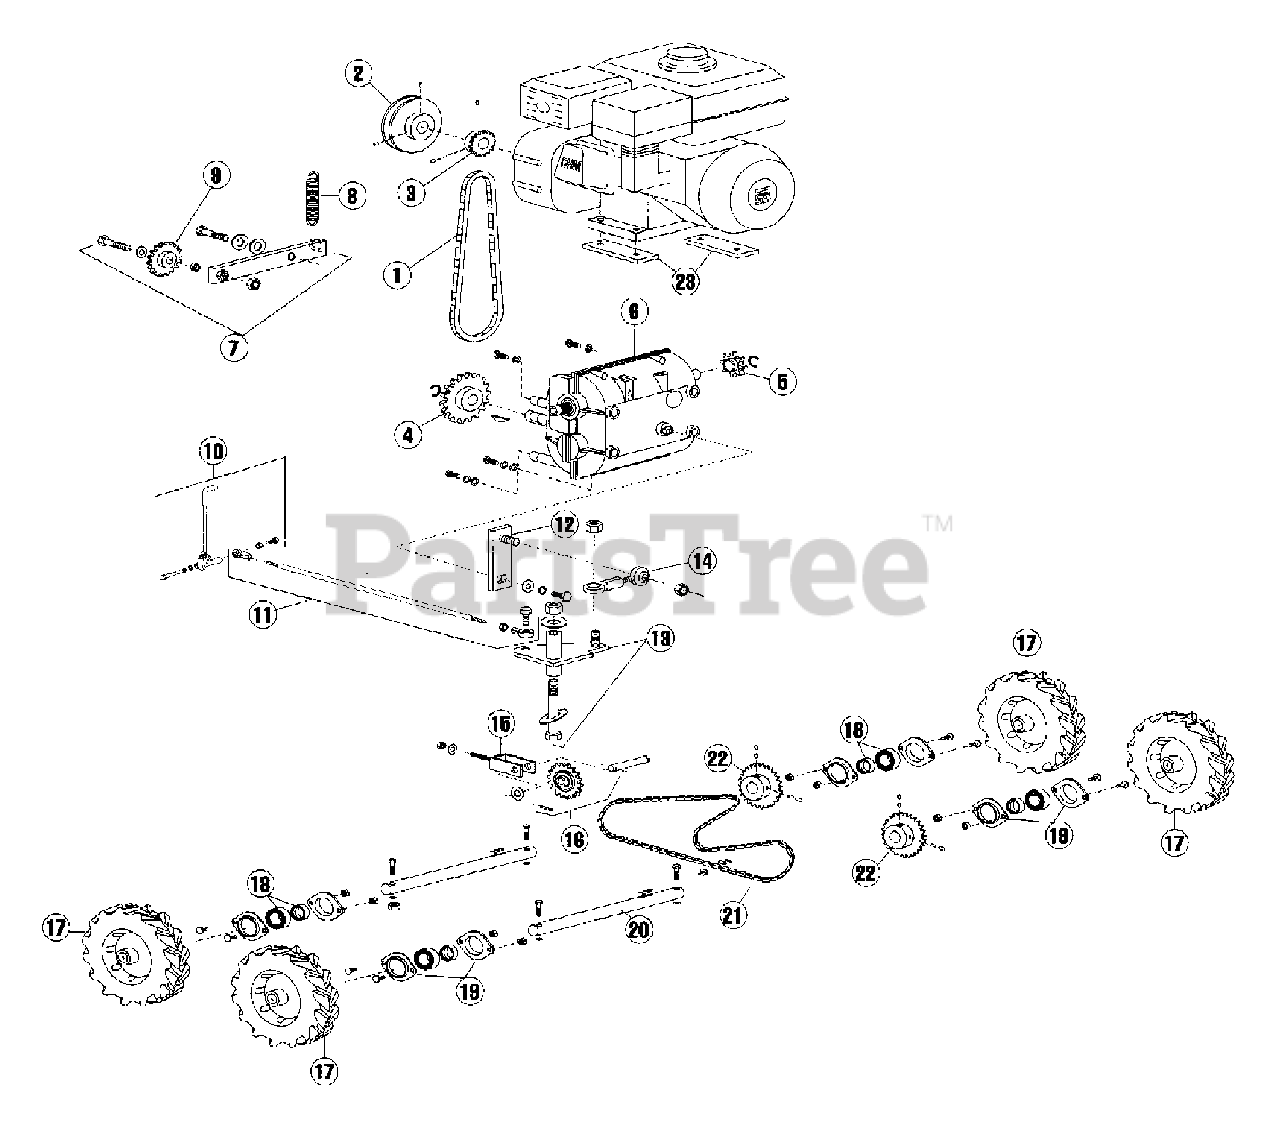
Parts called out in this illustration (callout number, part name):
1	Chain, transmission 26 5/8" length
2	V-pulley 4" special, with key
3	Sprocket with key
4	Sprocket with key and ring
5	Sprocket, transmission, 8 tooth
6	Transmission with hardware
7	Chain idler arm assembly
8	Spring, 3 3/4"
9	Sprocket, idler arm
10	Lever, shift kit
11	Linkage, shift
12	Arm, transmission shift with hardware
13	Bell crank shift kit
14	Rod end, linkage bell crank
15	Tensioner assembly, drive train
16	Sprocket, drive train tensioner
17	Wheel, 10" with hardware
18	Bearing, 1" with locking collar
19	Stamping kit, with fasteners (1" bearing)
20	Axle, wheel, with hardware
21	Chain, 55", drive
22	Sprocket, with key, rotor
23	Motor space plate kit with hardware
